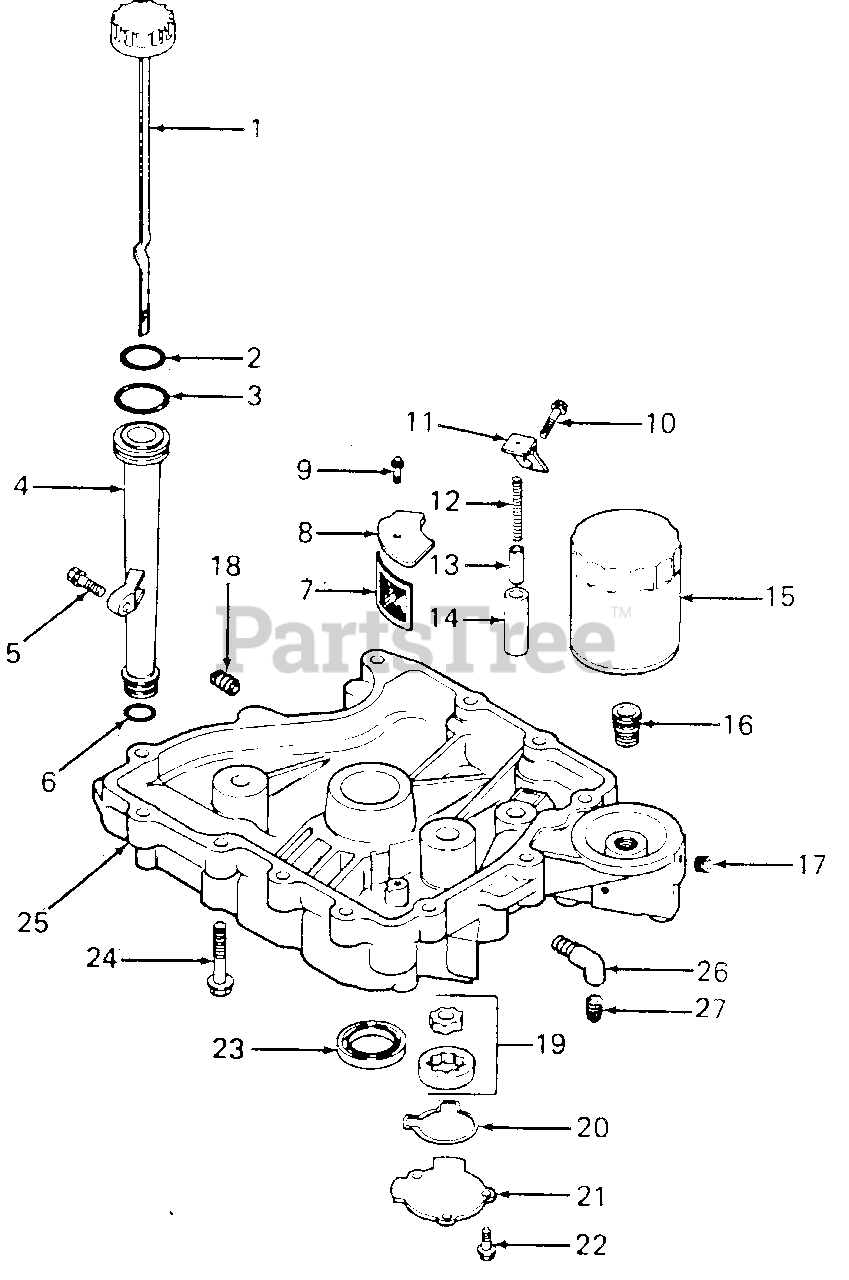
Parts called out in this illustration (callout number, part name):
2	O-Ring, Dipstick
3	O-Ring, Upper Oil Fill Tube
4	Tube, Oil Fill
5	Screw, Oil Fill Tube, M5 X 0.8 X 20
6	O-Ring, Lower Oil Fill Tube
7	Screen, Oil Pick-Up
8	Cover, Oil Pick-Up Screen
9	Screw, Screen Cover, M5 X 0.8 X 16
10	Screw, Oil Pump Relief Valve Bracket, M10 X 1.5 X 25
11	Bracket, Oil Pump Relief Bracket
12	Spring, Oil Pump Relief Valve
13	Piston, Oil Pump Relief Valve
14	Body, Oil Pump Relief Valve
15	Filter, Oil
16	Adapter, Oil Filter
17	Plug, Hex Ctsk, 1/8 NPTF
18	Plug, Sq Hd Solid, 3/8 NPTF
20	O-Ring, Oil Pump Cover
21	Cover, Oil Pump
22	Screw, Oil Pump Cover, M5 X 0.8 X 16
23	Seal, Oil
24	Screw, Oil Pan, M8 X 1.25 X 45
26	Tube, Oil Drain
27	Plug, Oil Drain
